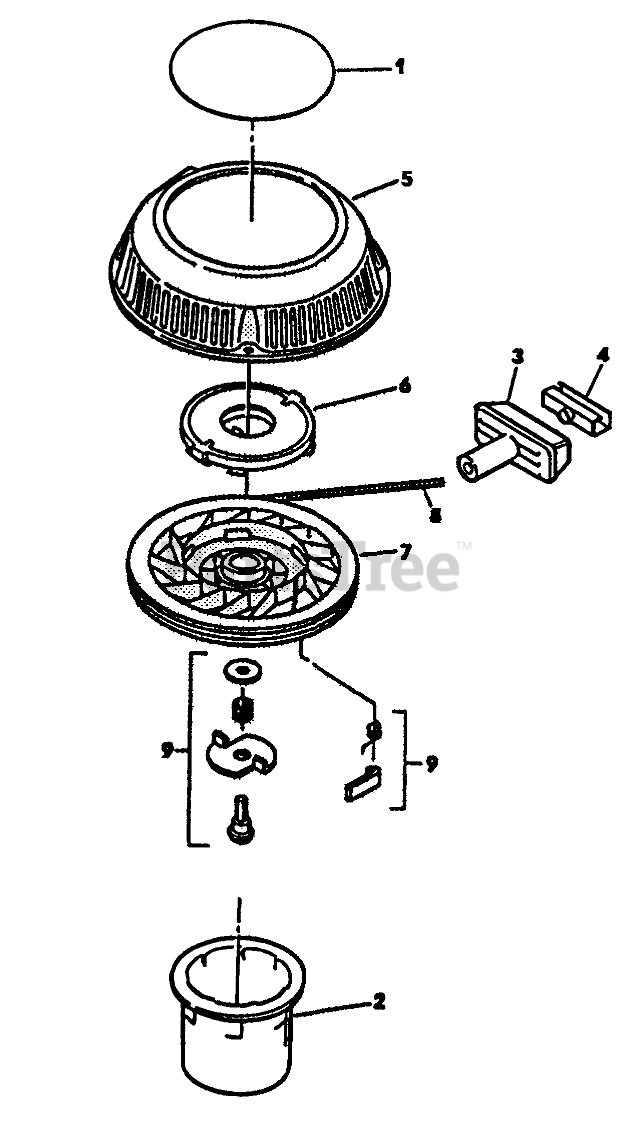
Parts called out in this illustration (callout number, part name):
1	DECAL-RECOIL S
2	HUB-STARTER E COMM.
3	HANDLE-START
4	CLIP-STARTER
5	STARTER HOUSING & SHAFT
6	Recoil Spring
7	PULLEY
8	ROPE-RECOIL
9	DOG KIT
